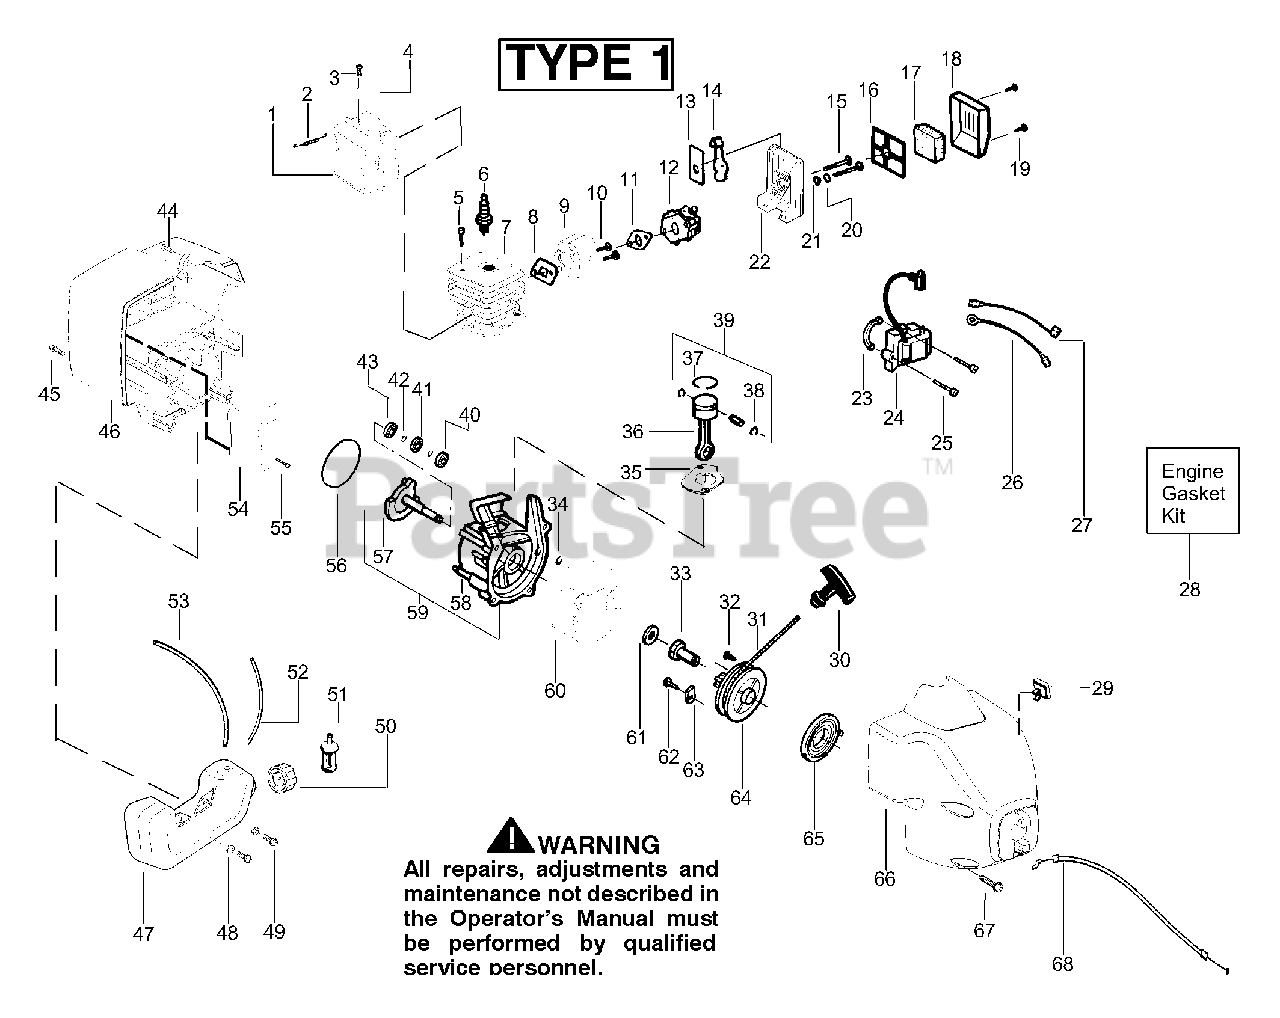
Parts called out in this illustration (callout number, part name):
1	Kit-Muffler
2	Muffler Spring
3	Screw-screen
4	Screen-Spark Arrestor
5	Screw-Cylinder
6	Spark Plug (RCJ-7Y)
7	Kit-Cylinder
8	Gasket-Cylinder/Carb.
9	Carb. Adapter
10	Screw-Carb Adptr.
11	Gasket-Carb.
12	Kit-Carb. Ass'y.
13	Choke Plate
14	Choke Shutter
15	Screw-Carburetor
16	Filter Support Plate
17	Air FIlter Foam
18	Air Filter Cover
19	Screw-Air Box
20	Choke Spacer
23	Spacer-Ignit. Module
24	Ignition Module
25	Screw-Ignit. Module
26	Assy-Ground Wire
27	Assy-Lead Wire
28	Kit-Engine Gasket
29	Kit-Switch-Off/On
30	Handle-Starter
31	Kit-Rope
33	Coupling-Drive
34	Ret. Ring/C'shaft
35	Gasket-Cylinder
36	Assy-Connecting Rod
37	Ring-Piston
38	Retainer-Piston Pin
39	Kit-Piston
40	Bearing-Outer
41	Seal-C'case
42	Ret. Ring-C'case
43	Bearing-Inner
44	Screw-Shd/Fan Hsg
45	Screw
46	Rear Shroud
47	Assy-Fuel Tank
48	Washer-fuel tank
49	Screw-Fuel Tank
50	Assy-Fuel Cap
51	Assy-Fuel Pickup
52	Fuel Line (Small)
53	Fuel Line (Large)
54	Shield-Heat
55	Screw-Heat Shield
56	O-ring-C'case
57	Assy-Crankshaft
58	Assy-Crankcase
59	Assy-c'case/c'shaft
60	Assy-Flywheel
61	Washer-Flat
62	Screw-Pulley
63	Retainer-Pulley
64	Kit-Starter Pulley
65	Spring-Starter
66	Assy.-Fan Hsg.
67	Screw
68	Assy-Throttle Cable
